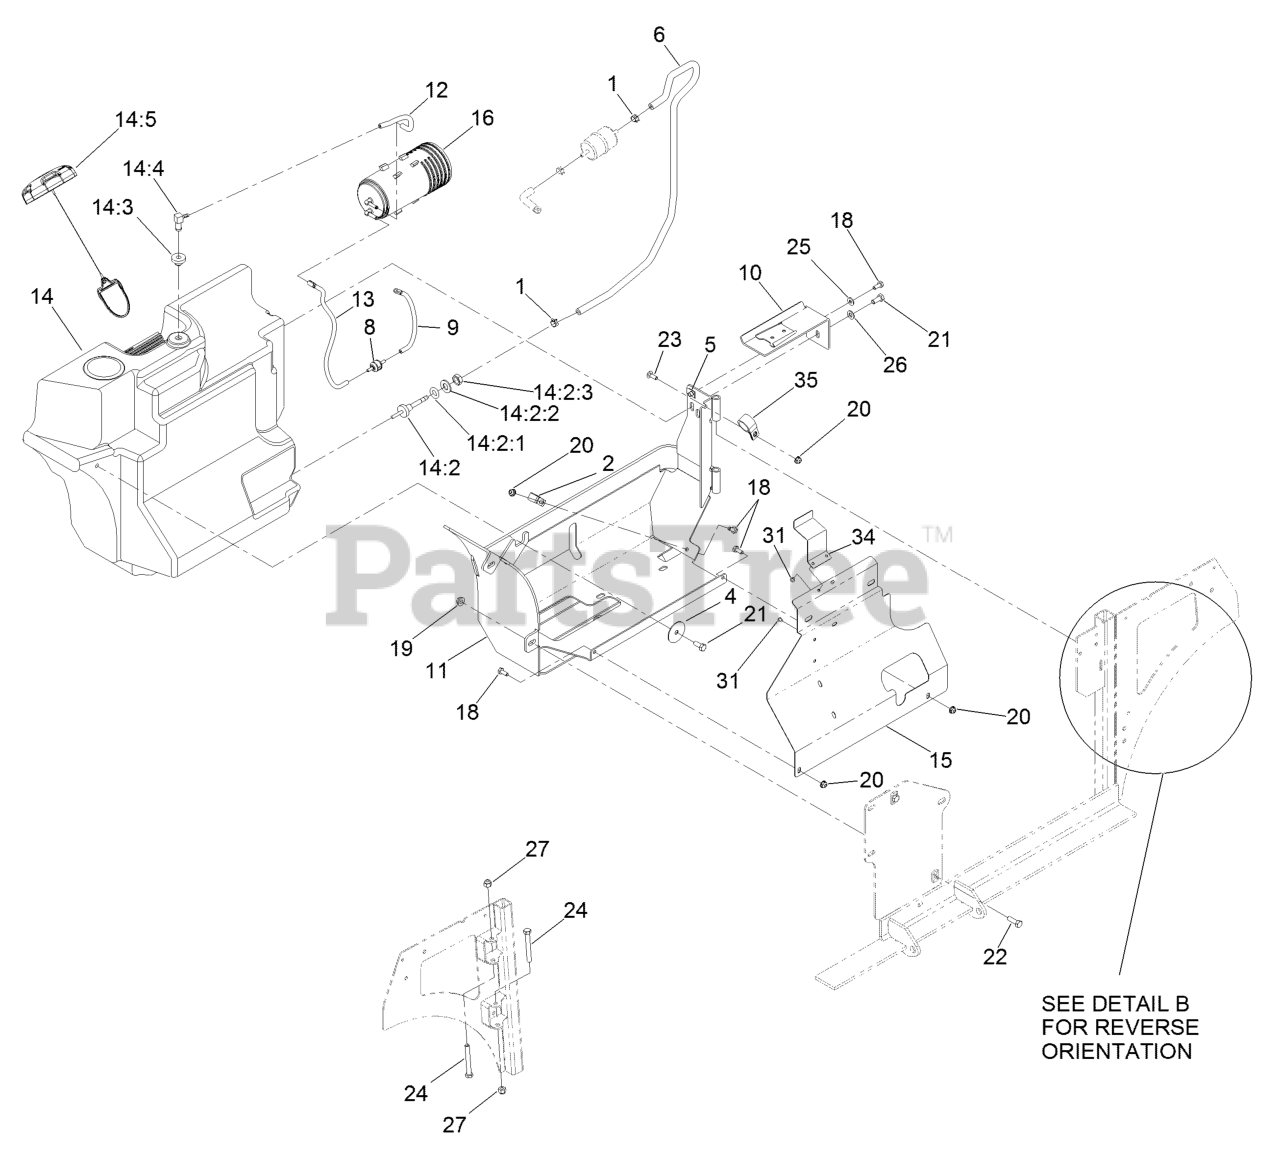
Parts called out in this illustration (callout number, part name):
1	CLAMP-HOSE
2	CLIP-LOOM
6	HOSE-FUEL
9	HOSE-VENT, FORMED
10	CANISTER BRACKET ASM
11	TANK FRAME ASM
12	HOSE-VENT, FORMED
13	HOSE-VENT, FORMED
14	FUEL TANK ASM
14:2	FITTING-FUEL, BULKHEAD
14:2:1	O-RING,BULKHEAD FITTING
14:2:2	WASHER-FLAT
14:2:3	NUT-JAM
14:3	BUSHING
15	PANEL-TANK SHIELD
16	CANISTER-CARBON, 800CC
18	SCREW-HH
21	SCREW-HH
22	SCREW-HH
23	BOLT-CARR
24	SCREW-CARR
25	WASHER-FLAT
26	WASHER-PLAIN
27	NUT-LOCK, NI
31	RIVET-POP
34	BRACKET-SHIELD, TANK
35	R-CLAMP
